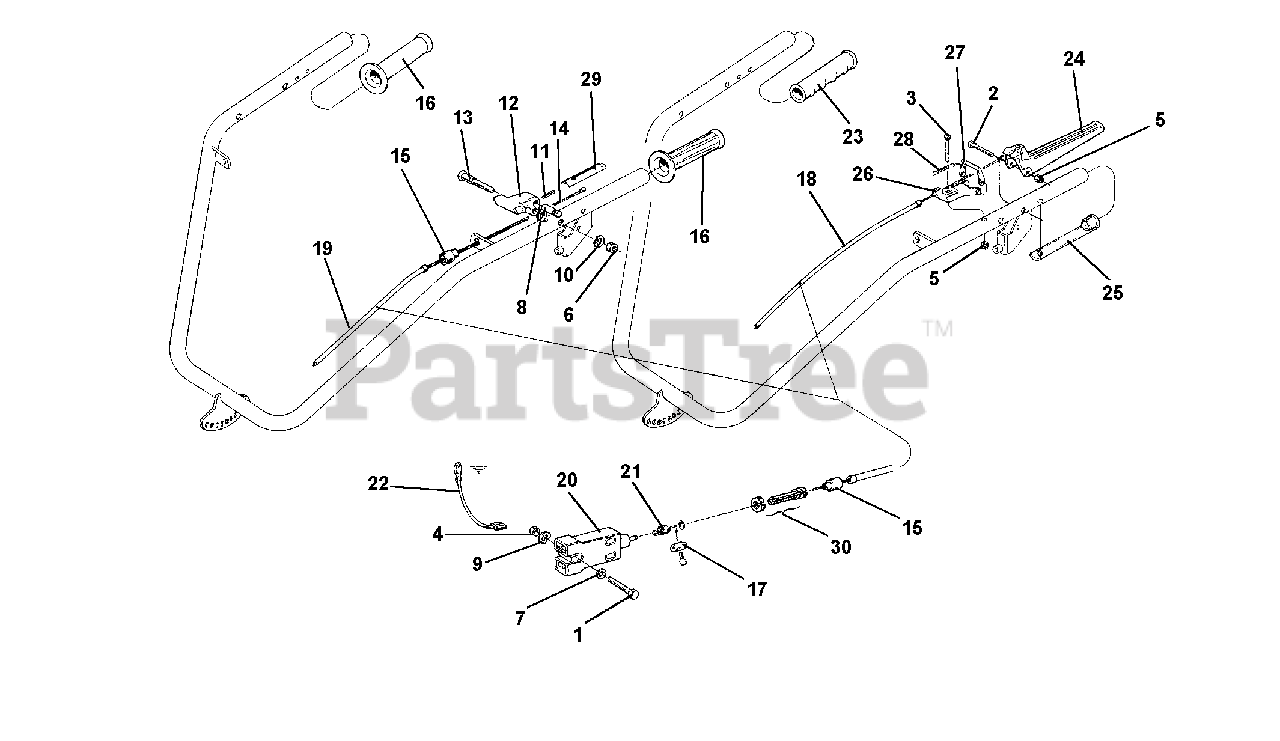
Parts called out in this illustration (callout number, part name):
1	SCREW TE M4 X 25
2	SCREW TE M6 X 45
3	SCREW TSV M6 X 40
5	NUT, SELF LOCKING M6
6	NUT, SELF LOCKING M8
7	FLAT WASHER 4.3
8	WASHER, FLAT 8.4
9	LOCK WASHER B 4.3
10	WASHER, LOCK 8.4
11	PIN, LOCKING 4 X 20
12	LOCKING LEVER
14	DRILLED PIN
15	END, SHEATH
16	KNOB RUBBER HOLE D 25
17	CABLE CLAMP
18	SHEATH CABLE
19	SHEATH CABLE
20	STOP SWITCH
21	SWITCH SPRING
22	SWITCH CABLES
24	MOVABLE MOTOR STOP BODY
26	SHEATH LOCK
27	MOVABLE BODY LOCK
29	RUN-STOP LABEL
30	ADJUSTING SCREW
